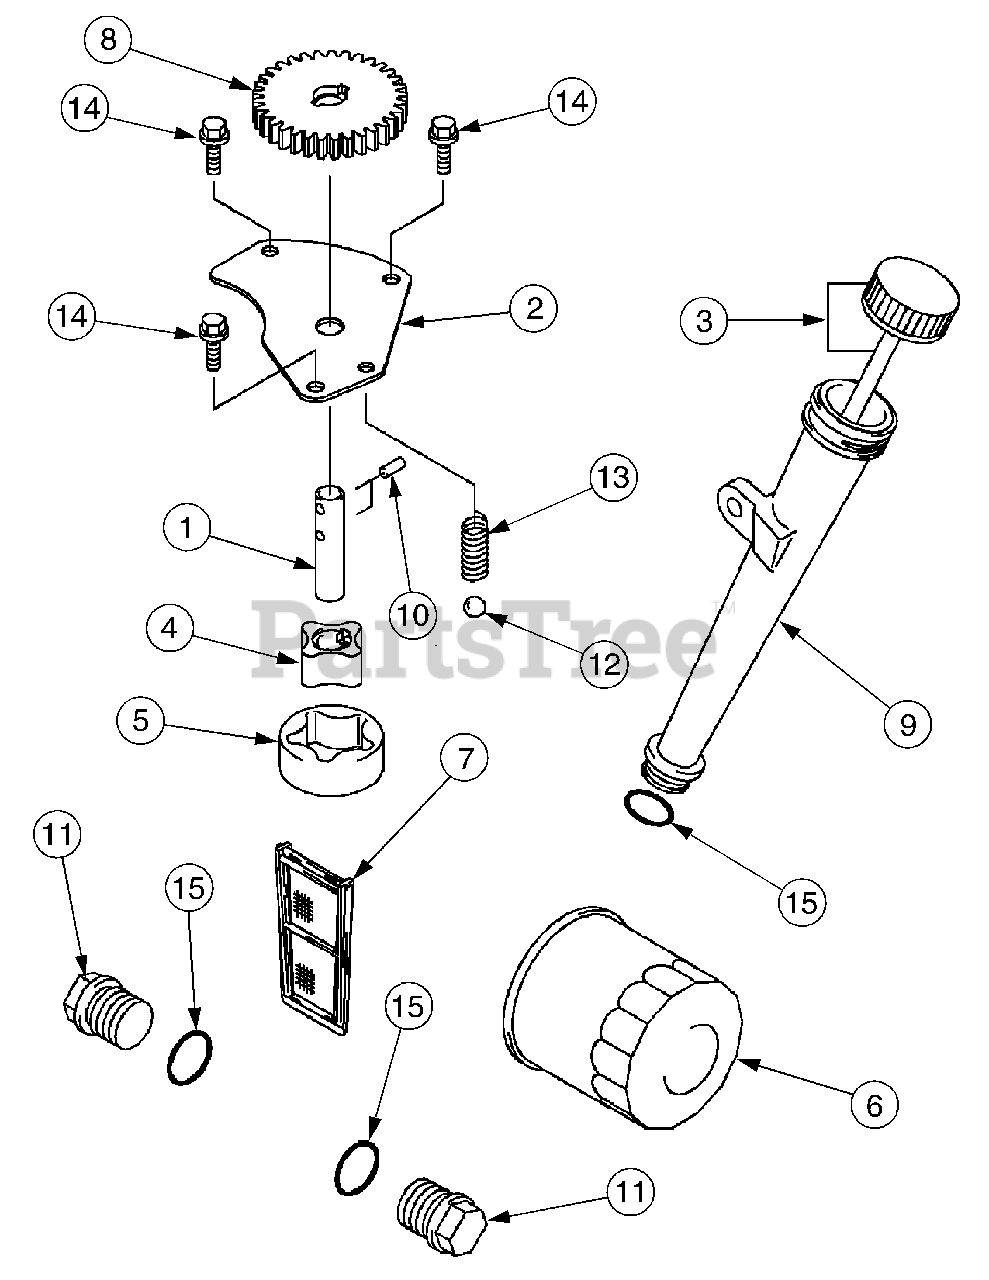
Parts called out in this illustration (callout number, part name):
1	Shaft
3	Dipstick Assembly
4	Rotor, Pump, (In)
5	Rotor, Pump, (Out)
6	Filter, Oil
7	Filter, Oil Screen
9	Tube, Dipstick/Oil Fill
10	Pin
11	Plug
14	Bolt, Flanged
15	O-Ring, 16mm
